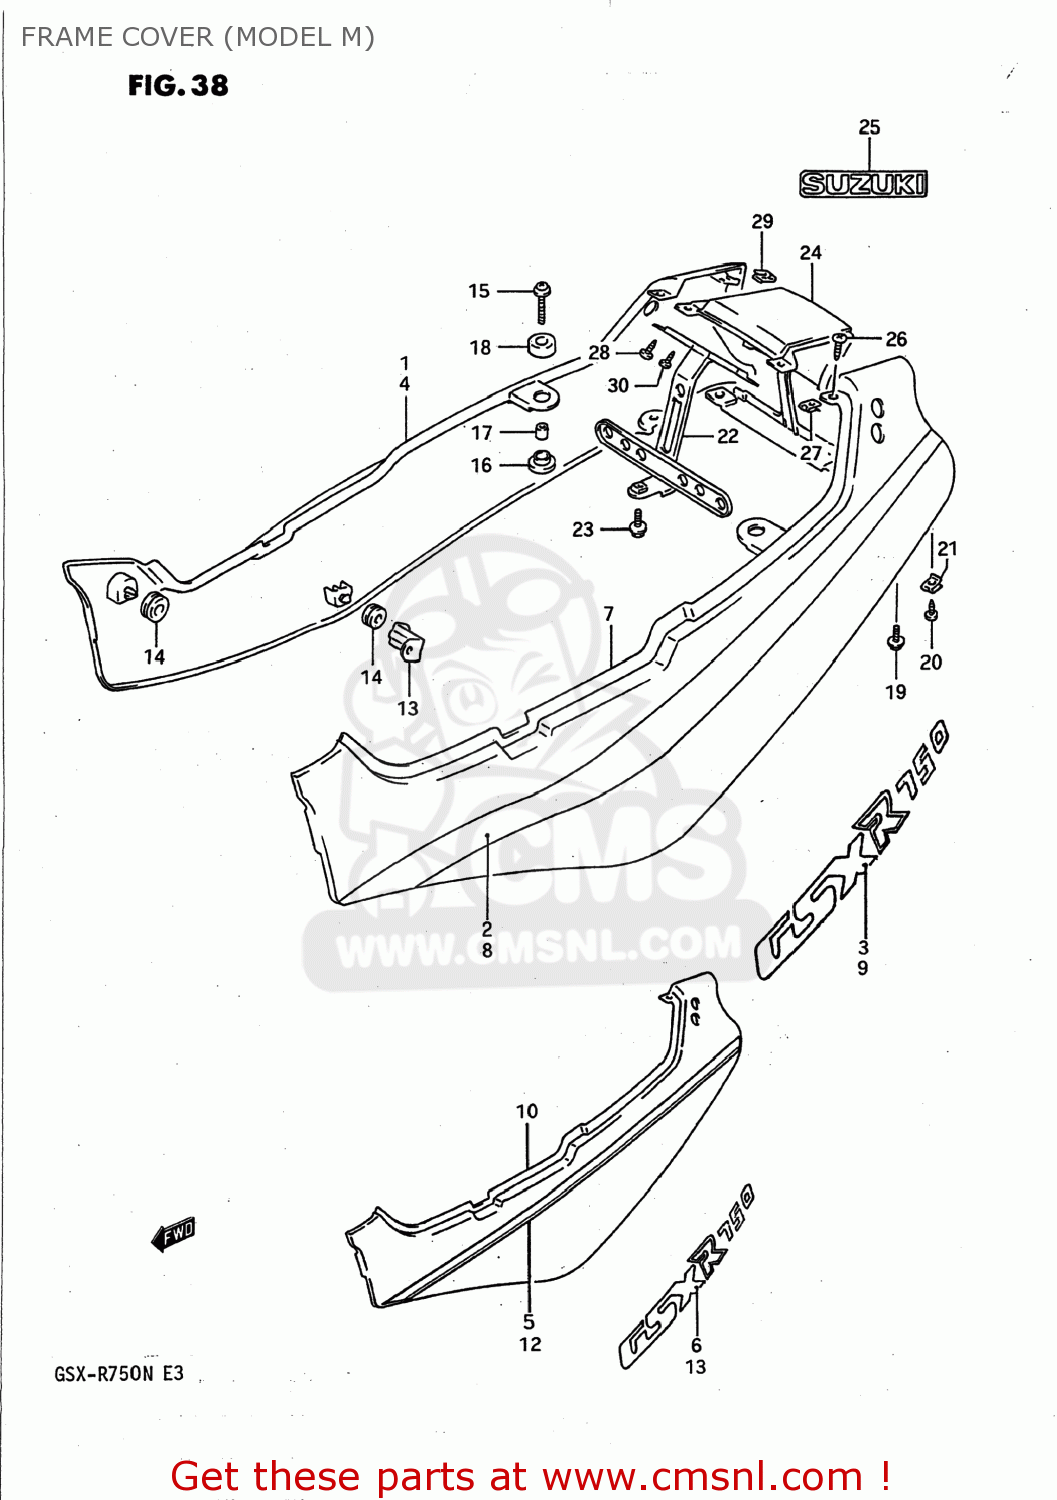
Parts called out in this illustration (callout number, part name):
1	COVER COMP,FRAME,RIGHT
2	TAPE,FRAME COVER,RIGHT (BLUE)
3	EMBLEM,FRAME COVER
4	COVER COMP,FRAME,RIGHT
5	TAPE,FRAME COVER,R
6	EMBLEM,FRAME COVER
7	COVER COMP,FRAME,LEFT
8	TAPE,FRAME COVER,LEFT (BLUE)
9	EMBLEM,FRAME COVER
10	COVER COMP,FRAME,LEFT
11	TAPE,FRAME COVER,LEFT
12	EMBLEM,FRAME COVER
13	BRACKET,FRAME COVER
14	CUSHION
15	SCREW (6X16)
16	CUSHION,FRAME COVER LWR
17	SPACER
18	CUSHION,TAIL COVER UPR
19	SCREW(6X30)
20	SCREW
21	NUT
22	BRACKET,TAIL LAMP
23	BOLT
24	COVER,FRAME CTR
25	EMBLEM
26	SCREW, BRACKET
27	NUT
28	SCREW, BRACKET
29	NUT
30	SCREW
